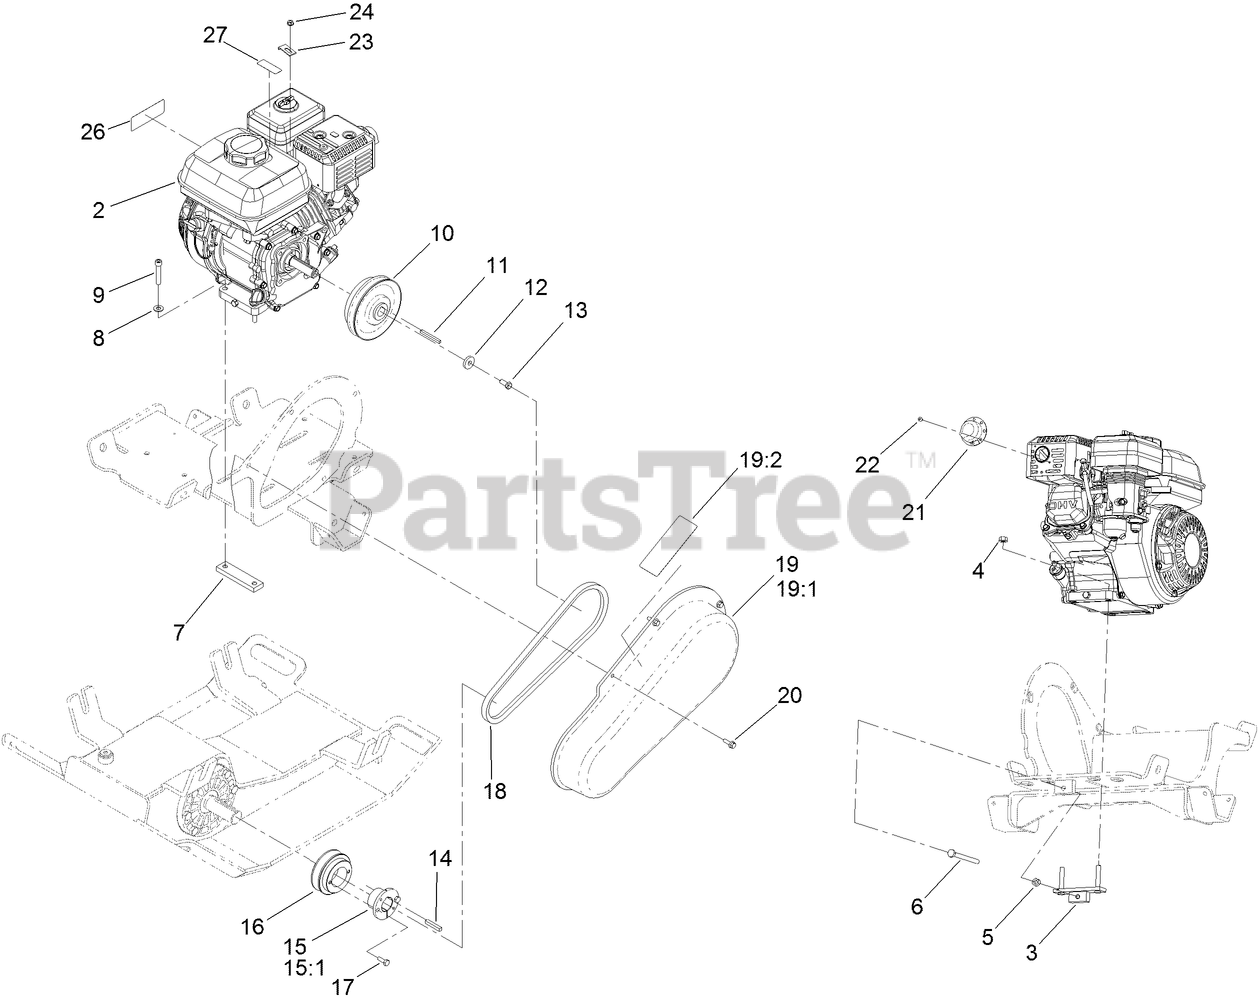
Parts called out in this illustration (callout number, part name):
2	ENGINE-HONDA, GX160
3	BRACKET-ADJUSTER, ENGINE
4	NUT-HF
5	NUT-HEX
6	SCREW
7	PLATE-NUT, ENGINE
8	WASHER-PLAIN
9	SCREW-HSH
10	CLUTCH, S-PLATE
12	WASHER
13	SCREW-HH
14	KEY-SQUARE
15	BUSHING-LOCKING
15:1	SCREW-SET
16	SHEAVE-ECCENTRIC
17	SCREW-HH
18	BELT-V
19	GUARD-BELT
19:2	DECAL-WARNING, PLATE
20	SCREW-HHF
21	DEFLECTOR
22	SCREW-SELF TAPPING
23	CLIP-THROTTLE
24	NUT-LOCK, FLANGE
26	DECAL-ARRESTER, SPARK
27	DECAL-WARNING, ETHANOL
